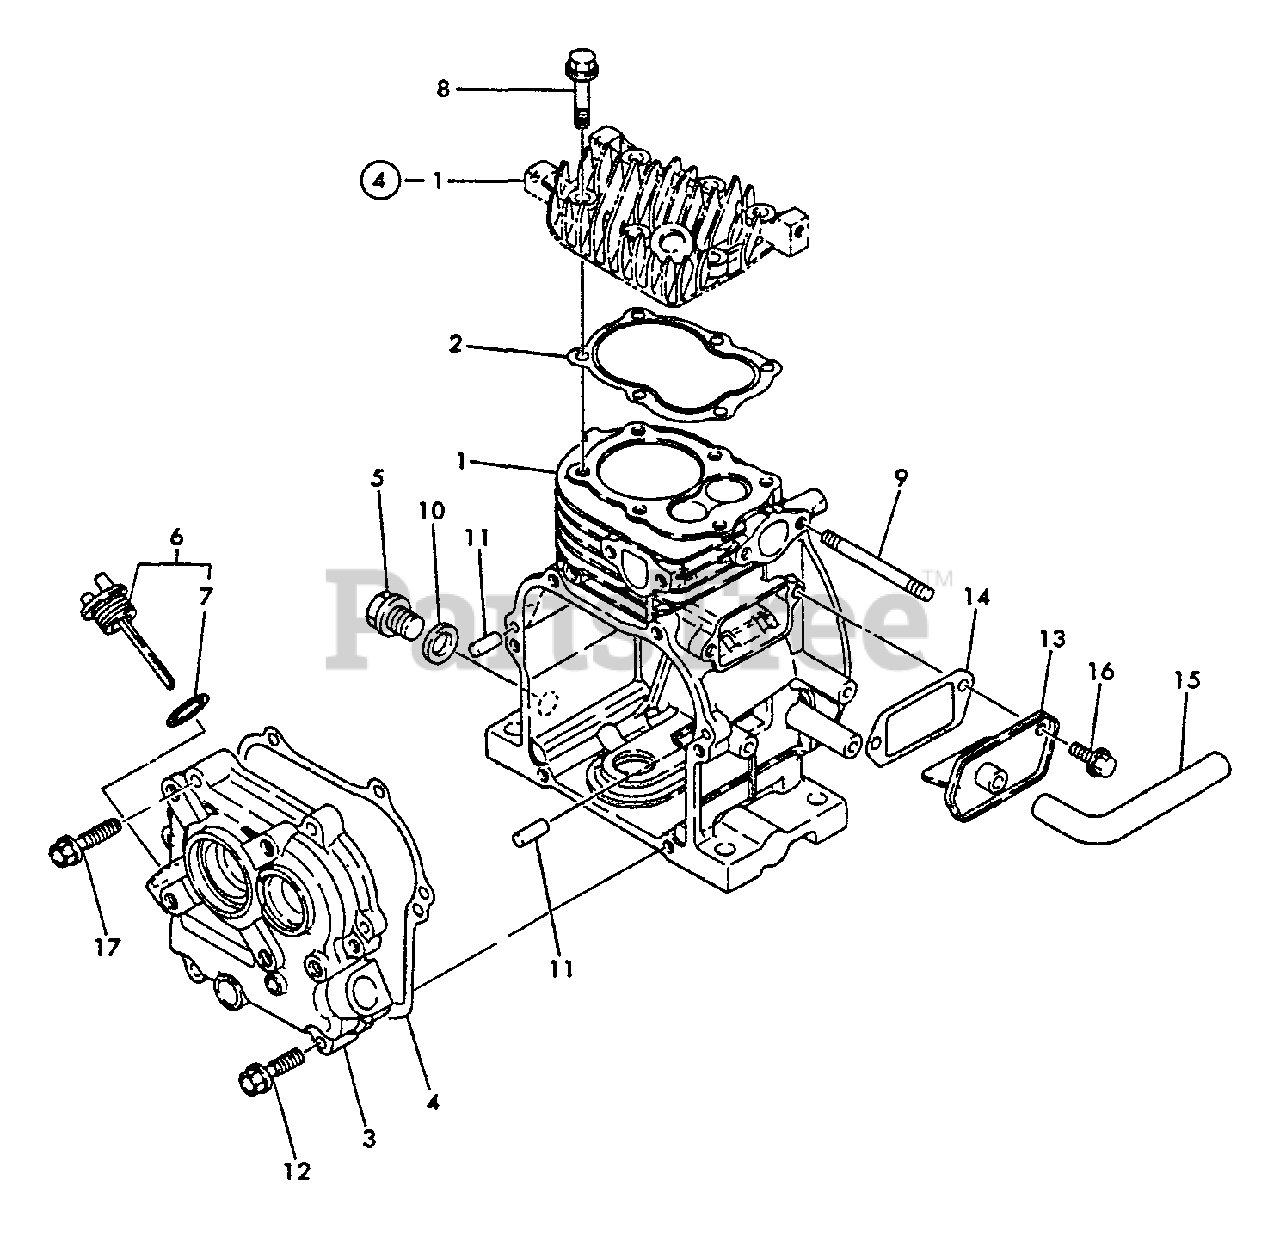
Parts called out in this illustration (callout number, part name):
1	CYLINDER ASSY
2	GASKET, CYLINDER
3	COVER, CRANKCASE
4	GASKET, CRANKCASE
5	PLUG, DRAIN
6	CAP ASSY
7	O-RING - 18
8	BOLT - 6X35
9	BOLT - 6X70
10	GASKET
11	PIN - 6X16
12	BOLT - 6X25
13	VENT, FUEL TANK
14	GASKET, BREATHER
15	PIPE - BREATHER
16	BOLT - 6X8 -- PLATED
17	BOLT - 6X32
